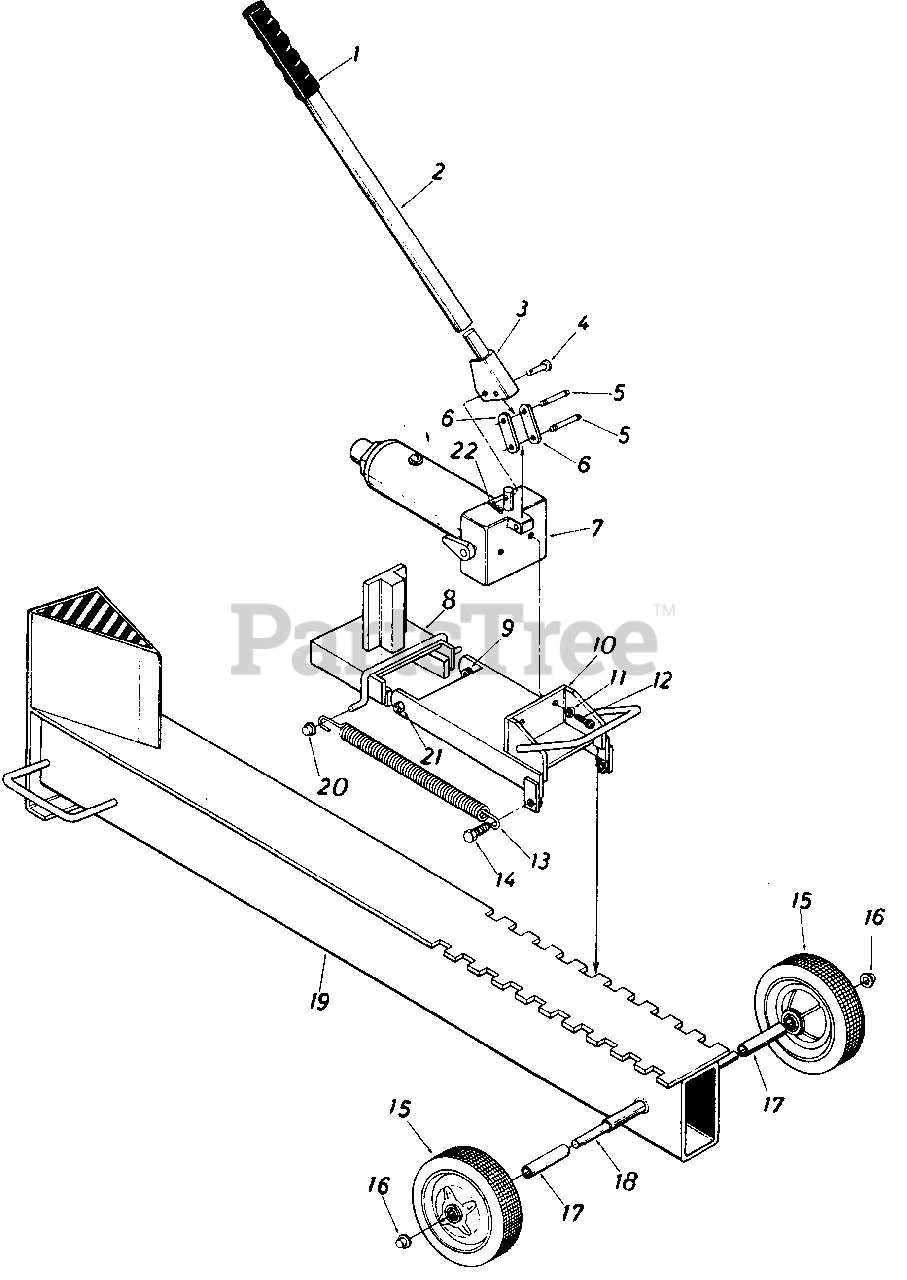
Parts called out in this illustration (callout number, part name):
1	Handle Grip
2	Handle 3/8" Dia. Rod
3	Handle Socket
4	Clevis Pin
5	Pin & Ring Assembly
7	Hydraulic Pump & Cylinder
8	Push Plate Ass'y.
9	Sockt Hd. Bolt 1/2-13 x . 75 Lg.
10	Cylinder Mounting
11	L.-Wash. 3/8" I.D.*
12	Socket Hd Bolt 3/8-16 x .75" Lg.
13	Extension Spring .75" O.D. x 10.75" Lg.
14	Hex L.-Bolt 3/8-16 x .75" Lg.*
15	Wheel 7.0" x 1.75"
16	1/2" Push Cap
17	Spacer
18	Axle 1/2" Dia. x 12" Lg.
19	Tube and Rail Ass'y.
20	1/2" Push Cap
21	Hex Cent. L.-Nut 1/2-13 Thd.
22	Hair Pin Cotter
